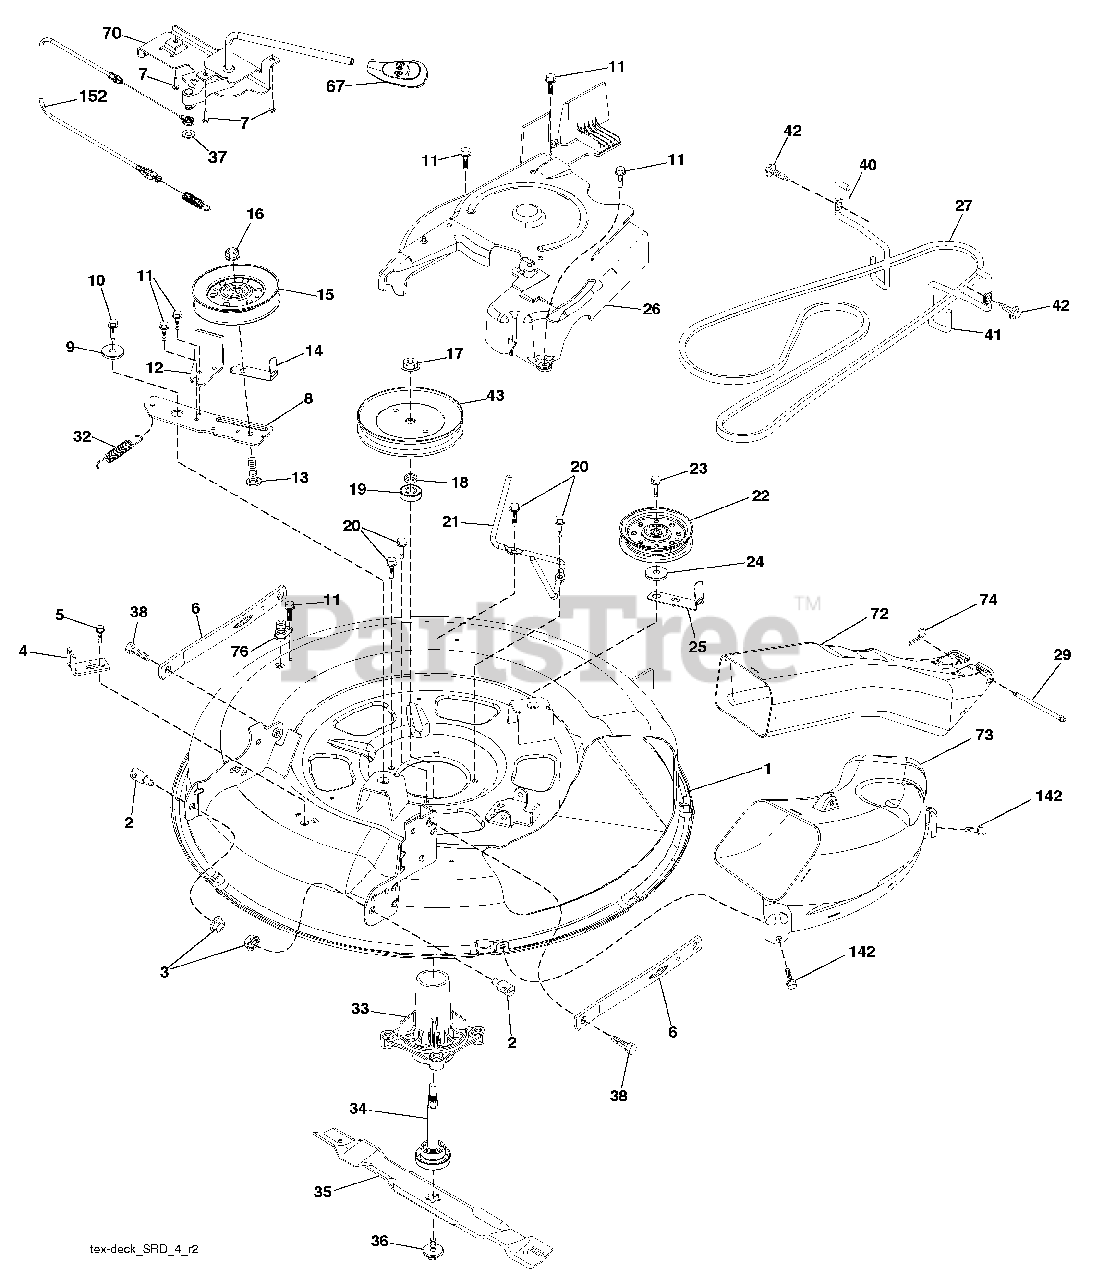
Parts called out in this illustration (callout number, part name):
1	Deck Weldment 30"Srd
2	Stud Fastner W/'D'anti-Rotatio
3	Nut Lock Hex Flange 5/16 - 18
4	Bracket Clutch Cable
5	Bolt 5/16-18
6	Arm Susp Mower Rear Srd
7	Screw #10 x 0.750 BOS Thread
8	Arm Idler 30"Srd
9	Spacer Retainer
10	Screw 3/8 - 16 X 1 Smgml Tap/R Blk
11	Screw Thd Roll 1/4 - 20 X 5/8
12	Arm Brake Mower 38" RH Tex
13	Bolt Carr Sh 3/8 - 16 X 1 - 1/2 Gr5
14	Keeper Belt Idler
15	Pulley Idler V-Groove Dim 4.25
16	Nut Lock FlG 3/8 - 16 unc
17	Nut Flange Lock Top
18	Washer Spacer Mandrel
19	Bearing Ball Mandrel
20	Screw Thd Roll Dod Pt Hex
21	Keeper Belt Mandrel 30"
22	Pulley Idler Flat Unplated
23	Screw Thdrol 3/8 - 16 X 1-3/4
24	Washer 13/32 X 1 - 1/4 X 12 Ga
25	Keeper Belt 30"Srd
26	Cover Mandrel Mwr 30"Black
27	V-Belt 88.45 GND DR/30" MWR
29	Hinge Pin
32	Spring Return Deck 38/46"
33	Housing Mandrel 4pt Service
34	Shaft Asm Mndrl N/Greaseable38
35	Blade Mower Bagging Srd
36	Bolt/Washer Asm 7/16 - 20 unf
37	Washer 13/32 x 13/16 x 16 Ga.
38	Bolt Shoulder
40	Keeper Belt Engine LH
41	Keeper Belt Engine RH
42	Screw Hexwsh THDR 3/8-16 x 3/4 BL
43	Pulley Mandrel 6 5 Pd 30"
67	Handle clutch cable
70	Clutch Asm. Manual
72	Chute Upper SRD 30R
73	Chute Lower SRD 30R
74	Retainer Spring
76	Washout Port
142	Screw 3/8-16 x 3/4
152	Manual Clutch Cable
